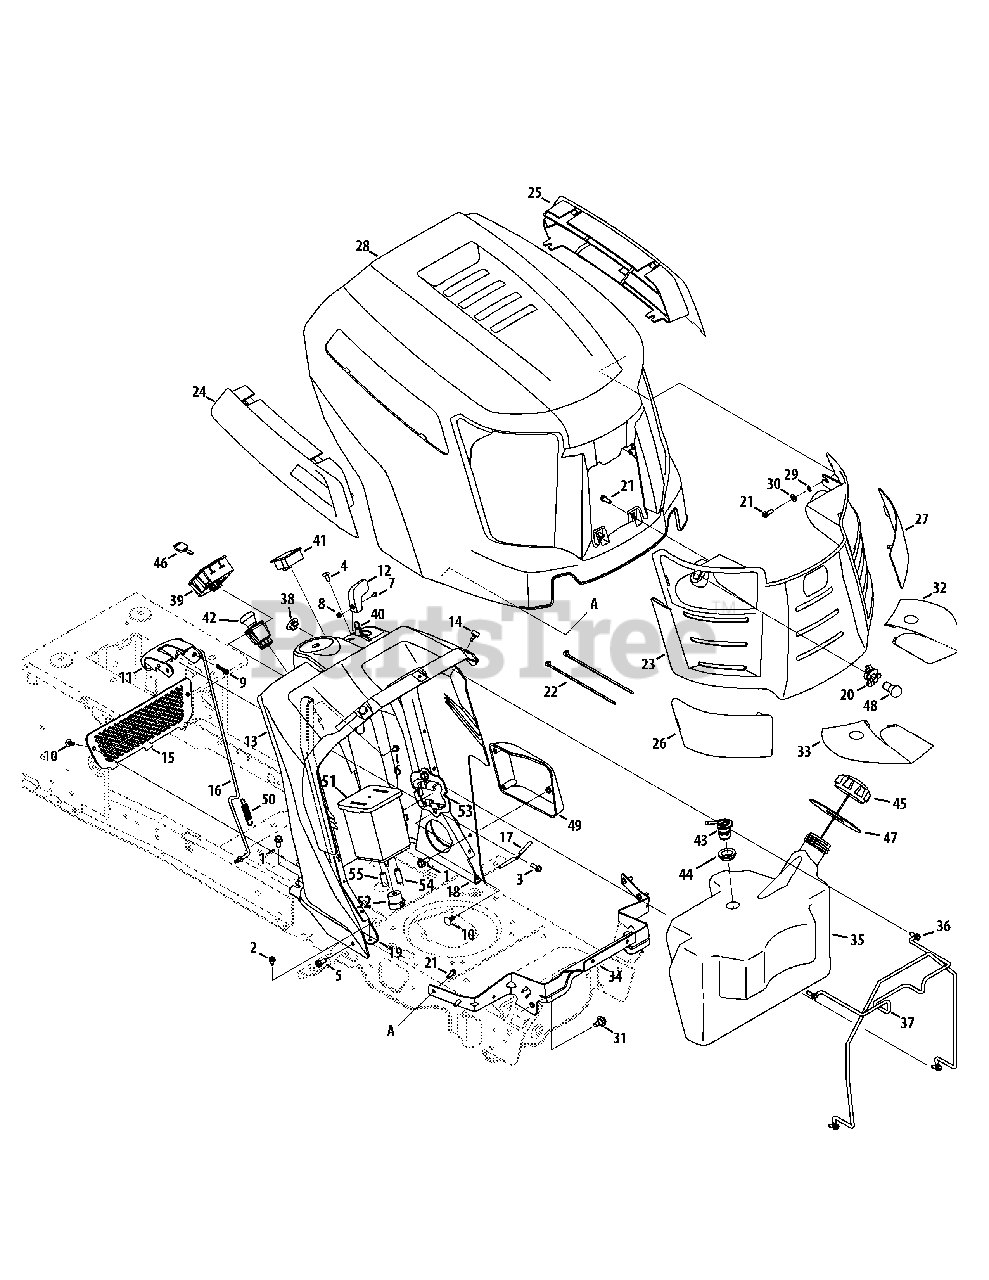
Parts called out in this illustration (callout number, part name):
1	Screw, Self-tapping, 5/16-18, .750
2	Screw, Self-tapping, 1/4-20, 0.500
3	Screw, HL, 1/4-15, 0.750
4	Screw, Ab, 1/4-14, 0.625,
5	Screw, Self-tapping, 5/16-18, 0.750,
6	Screw, Self-tapping, 1/4-20 x .625
7	Screw, Mach, #8-32, 0.375
8	Nut, Hex, #8-32
9	Pin, Cotter, Bow-Tie 72
10	Clip, Ratchet, .250 Dia
11	Lever, Dash, Cruise/Brake
12	Knob, Throttle
13	Dash Panel, A-Style
14	Bumper, .62 Dia X .3
16	Rod, Control, Latch Cub
17	Rod, Lever, Bent
18	Support, Dash, Plate LH
19	Support, Dash, Plate RH
20	Socket, Lamp
21	Screw, 1/4 Dia, .750
22	Tie, Cable, Push Mount 7.5 Lg
23	Grille Ass’y (Incl. 26, 27, 32 & 33)
24	Scoop, Hood, RH A-Style
25	Scoop, Hood, LH A-Style
26	Lens, Hood, RH A-Style
27	Lens, Hood, LH A-Style
28	Hood, A-Style
29	Washer, Lock, 1/4, External
30	Washer, Flat, .271, .630, .065
31	Screw, Shoulder, .43x.29, 5/16-18
32	Reflector, Cub A Style, LH
33	Reflector, Cub A Style, RH
35	Tank, Fuel, 3.30 Gal.
36	Screw, Self-tapping, 1/4-20, .75
37	Rod, Support, Fuel Tank
38	Plug, Choke
39	Module Switch, Ignition
40	Cable, Throttle/Choke, 38"
41	Meter, Indicator
42	Switch, Electric PTO, Yellow
43	Valve, Rollover Grommet
44	Grommet, Rubber, 23.0 ID
45	Cap, Fuel
46	Key, Ignition
47	Gasket, Fuel Tank
48	Lamp, 12v
49	Cover, Power Steering Motor
50	Spring, .500 Dia. x 2.733
51	Canister, Carbon, 5 Gallon (CA)
52	Filter, Vent, Canister (CA)
53	Bracket, Adapter, Canister (CA)
54	Hose, Fuel, Low Perm, 3/16 Wht (CA)
55	Hose, Fuel, Low Perm, 7/32 Yel (CA)
